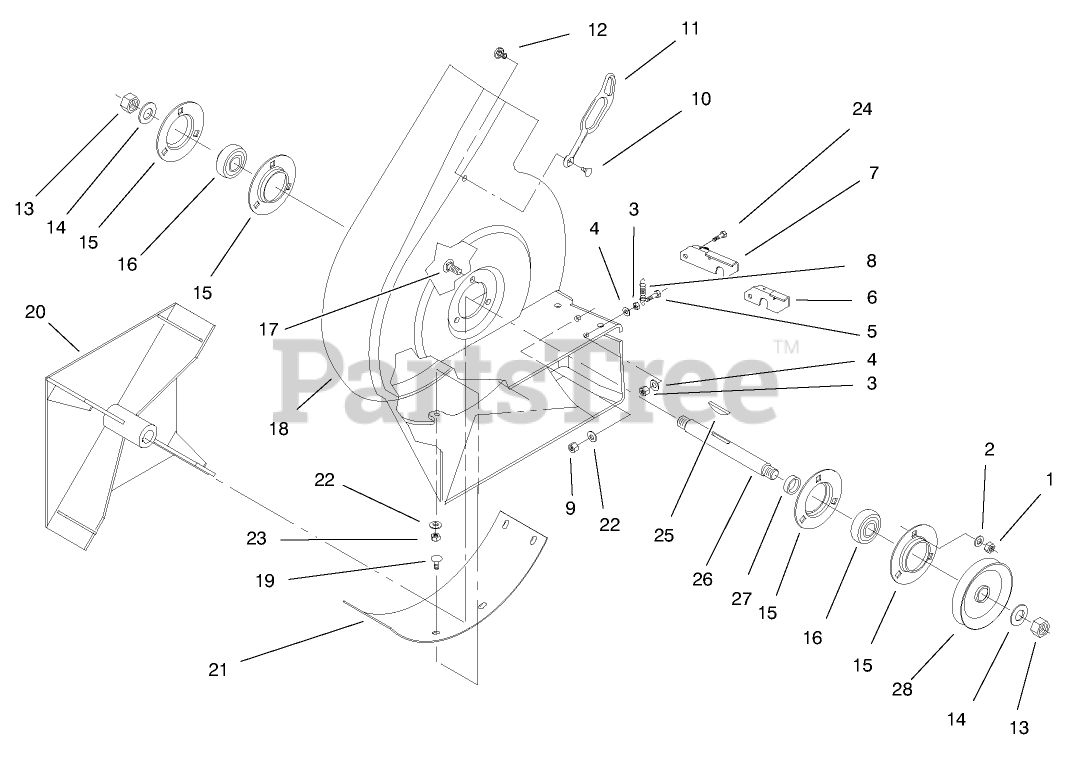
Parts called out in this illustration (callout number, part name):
1	NUT-HEX
2	WASHER-LOCK
3	NUT-HEX
4	WASHER-FLAT
5	SCREW-HWH
8	SPRING-EXTENSION
9	NUT-LOCK, NI
10	FASTENER-PANEL
11	RETAINER-DUCT
12	SPACER-INTERLOCK
13	NUT-JAM
14	WASHER-LOCK
15	FLANGE
16	BEARING-BALL
17	SCREW-CARR
22	WASHER-FLAT
23	NUT-LOCK, NI
24	SCREW-HH
26	SHAFT-BLOWER
27	SPACER
28	PULLEY-BLOWER
